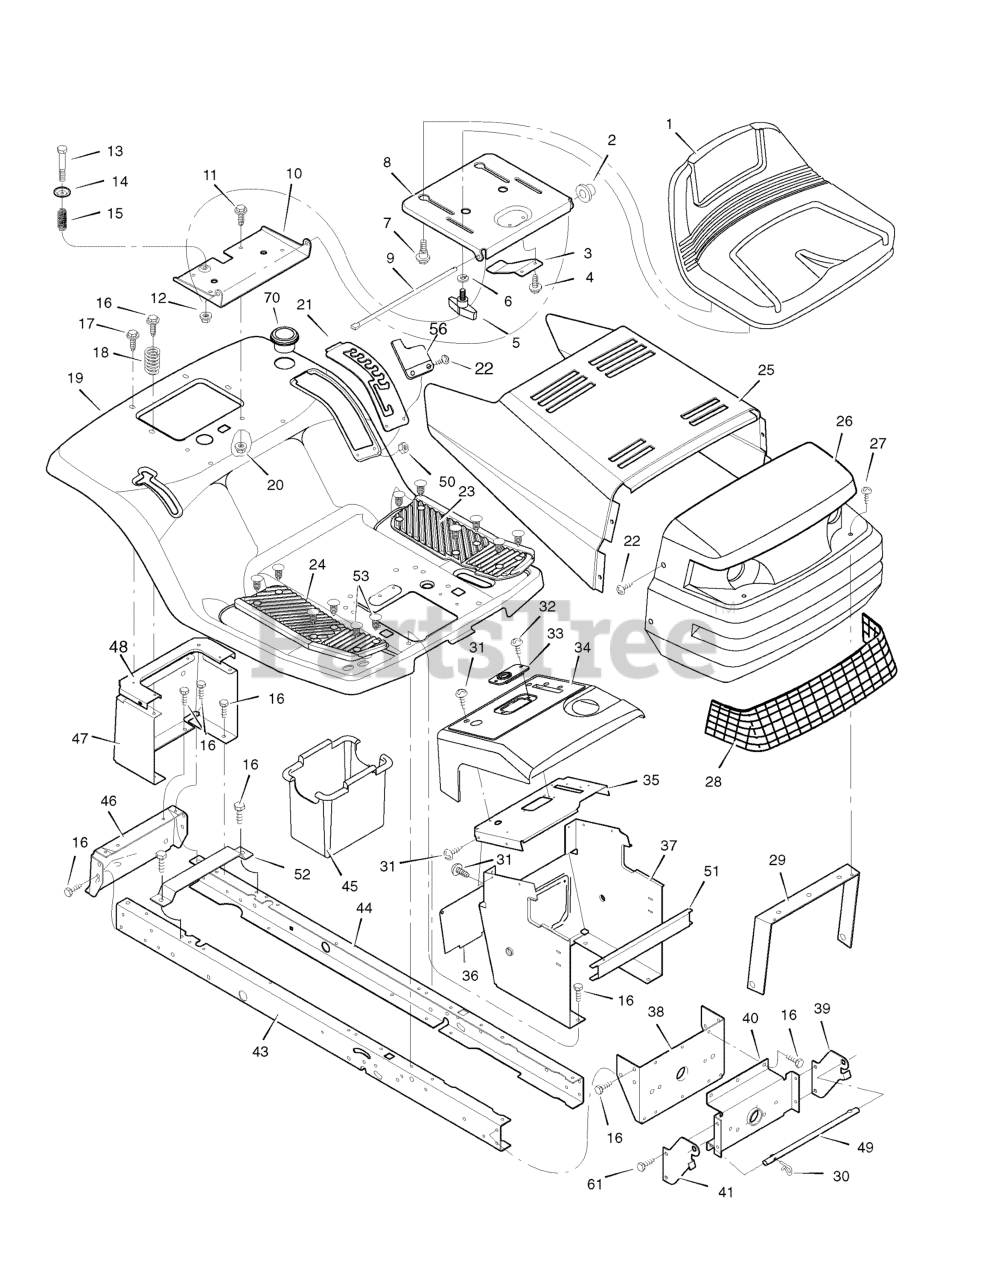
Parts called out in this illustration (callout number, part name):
2	Cap, Push 0n
5	Bolt, Wing
6	Washer
7	Bolt, Shoulder
8	Support, Seat
9	Rod, Pivot
10	Bracket, Pivot
11	Bolt
13	Bolt, Shoulder
20	Nut
21	Plate, Index
23	Mat, Left
24	Mat, Right
27	Lens, Left
28	Housing, Left Headlamp
29	Lens, Right
30	Housing, Right Headlamp
33	Bearing, Steering
36	Panel, Access
37	Support, Dash
38	Support, Rear Hanger
39	Support, Left Grille
40	Axle, Hanger
41	Support, Right Grille
43	Frame, Right
44	Frame, Left
45	Container, Battery
46	Plate, Hitch
47	Plate, Rear
48	Top, Rear Plate
49	Rod, Pivot
52	Bracket, Battery Support
53	Fastener, Panel
56	Cover, Detent
61	Bolt, Shoulder
70	Holder, Cup
